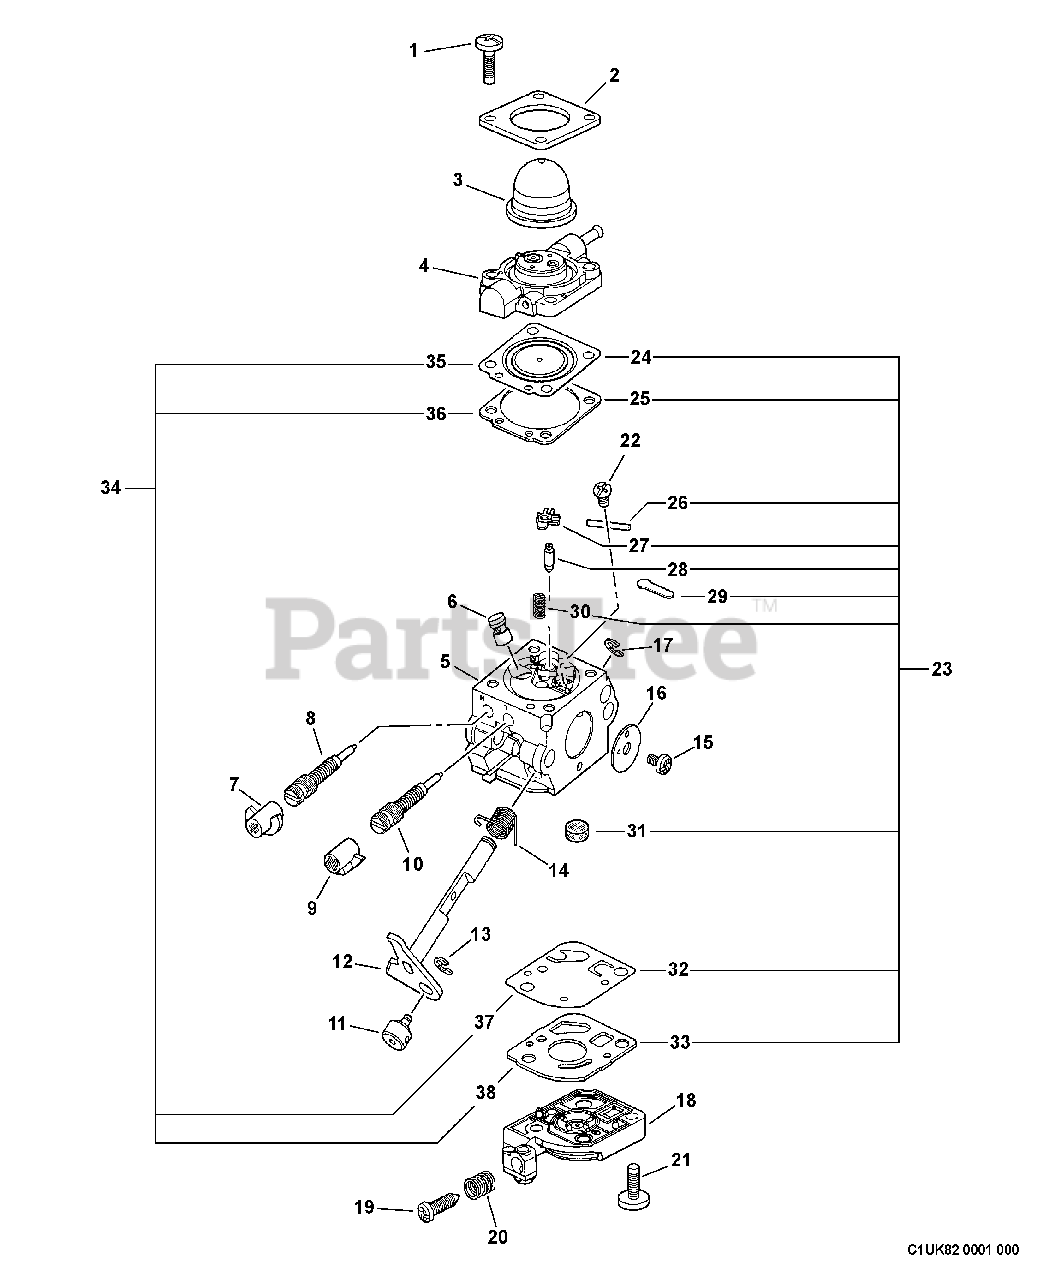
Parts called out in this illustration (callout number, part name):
1	SCREW, RETAINER
2	RETAINER, PURGE BULB
3	BULB, PURGE
4	BASE, PURGE
5	BODY, CARBURETOR
6	NOZZLE, CHECK VALVE
7	CAP, LIMITER
8	NEEDLE - HIGH SPEED
9	CAP, LIMITER
10	NEEDLE - LOW SPEED
12	SHAFT, THROTTLE
13	RING, RETAINING
14	SPRING, RETURN
16	VALVE, THROTTLE
17	RING, RETAINING
18	BASE, PURGE
19	SCREW, IDLE ADJUST
20	SPRING, IDLE ADJUST
21	SCREW, PUMP COVER
22	SCREW, METERING LEVER PIN
23	REPAIR KIT
24	DIAPHRAGM, METERING
25	GASKET, METERING
26	PIN, METERING LEVER
27	LEVER, METERING
28	VALVE, INLET NEEDLE
29	PLUG, WELCH
30	SPRING, METERING LEVER
31	STRAINER
32	DIAPHRAGM, PUMP
33	GASKET, PUMP
34	DIAPHRAGM/GASKET KIT
35	DIAPHRAGM, METERING
36	GASKET, METERING
37	DIAPHRAGM, PUMP
38	GASKET, PUMP
